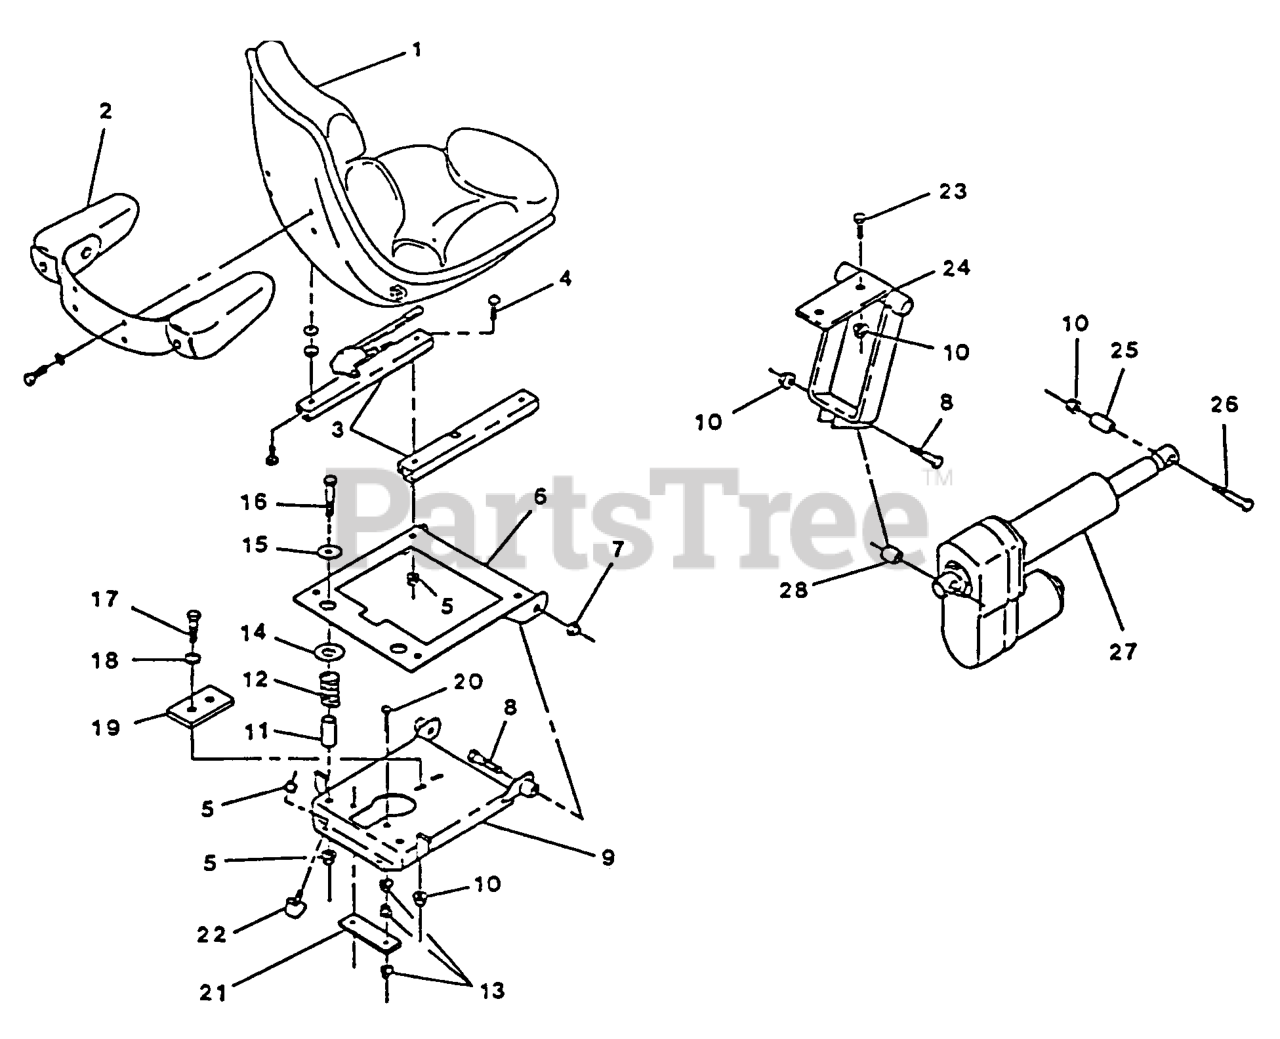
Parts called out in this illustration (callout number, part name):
11	BUSHING,SPRING GUIDE
12	SPRING-INDICATOR, REVERSE
22	BUMPER-RUBBER
